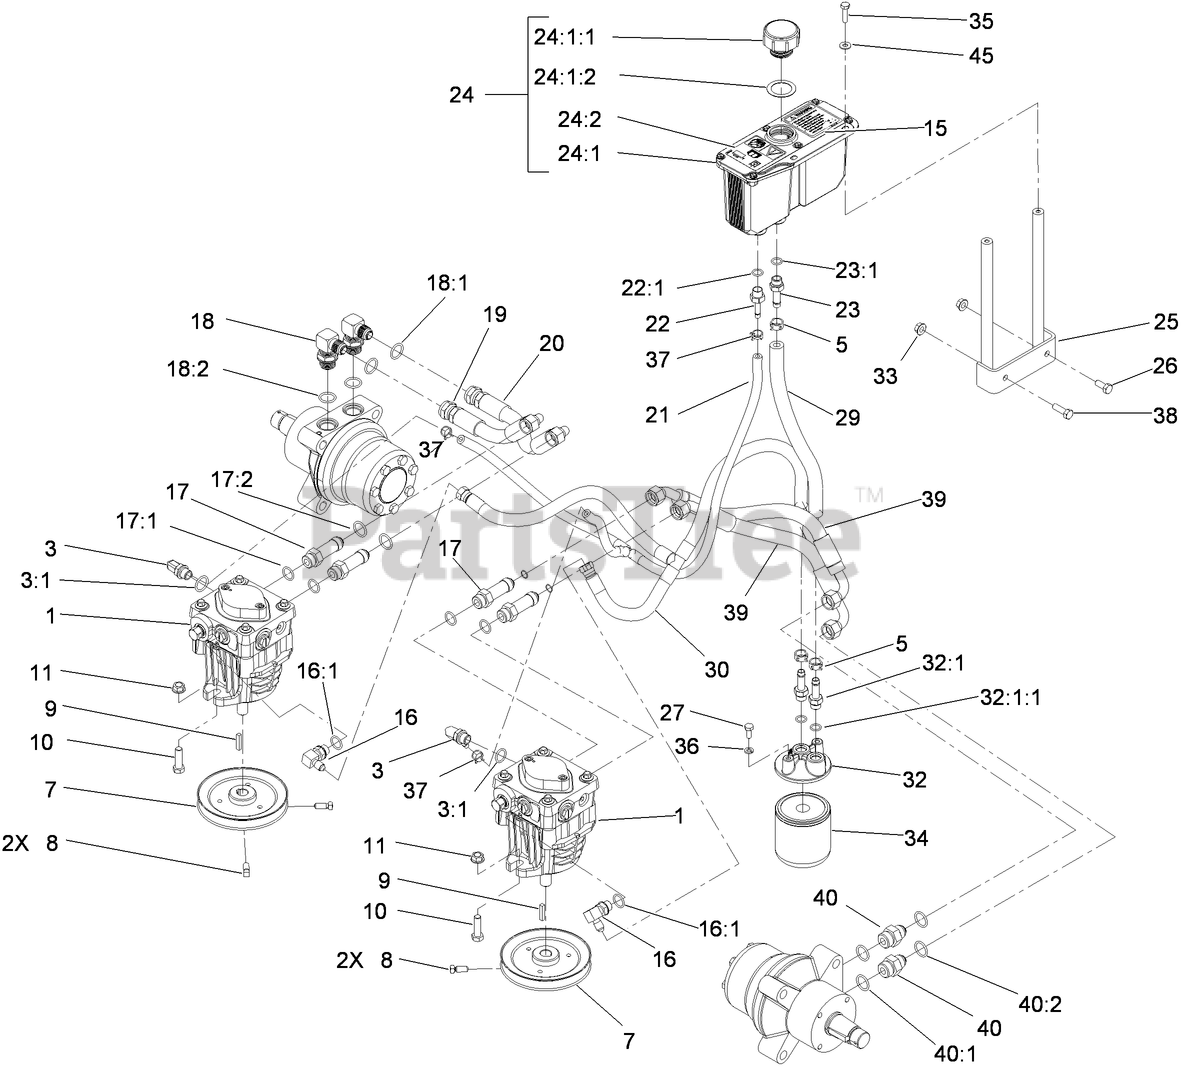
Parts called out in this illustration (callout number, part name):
1	PUMP-HYD
3	ELBOW-90 DEG
3:1	O-RING
5	Clamp-Hose
7	PULLEY
8	SCREW-SET
10	SCREW-HH
11	NUT-HHF, WHIZ
15	DECAL-EXHAUST
16	FITTING-ELBOW, 90 DEG
16:1	O-Ring
17	ADAPTER-HYD, STRAIGHT
17:1	O-RING
17:2	O-Ring
18	FITTING-HYD, 90 DEG
18:1	O-Ring
18:2	O-RING
19	HOSE-FRONT
20	HOSE-REAR, RH
21	HYD HOSE ASM
22	Adapter-Straight
22:1	O-RING
23	ADAPTER-STRAIGHT
23:1	O-RING
24	HYD RESERVOIR ASM
24:1	Reservoir-HYD
24:1:1	CAP-RESERVOIR, HYD
24:1:2	GASKET-CAP
24:2	DECAL-WARNING
25	STAND-RESERVOIR
26	SCREW-HH
27	SCREW-HH
29	HYD HOSE ASM
30	HYD HOSE ASM
32	Filter Head ASM
32:1	ADAPTER-STRAIGHT
32:1:1	O-RING
33	NUT-HF
34	FILTER-OIL, HYD
34	FILTER-OIL, HYD (WINTER)
35	SCREW-HH
36	WASHER-LOCK
37	Clamp-Hose
38	SCREW-HH
39	HOSE-LH
40	Fitting-Straight
40:1	O-RING
40:2	O-Ring
45	WASHER-FLAT
